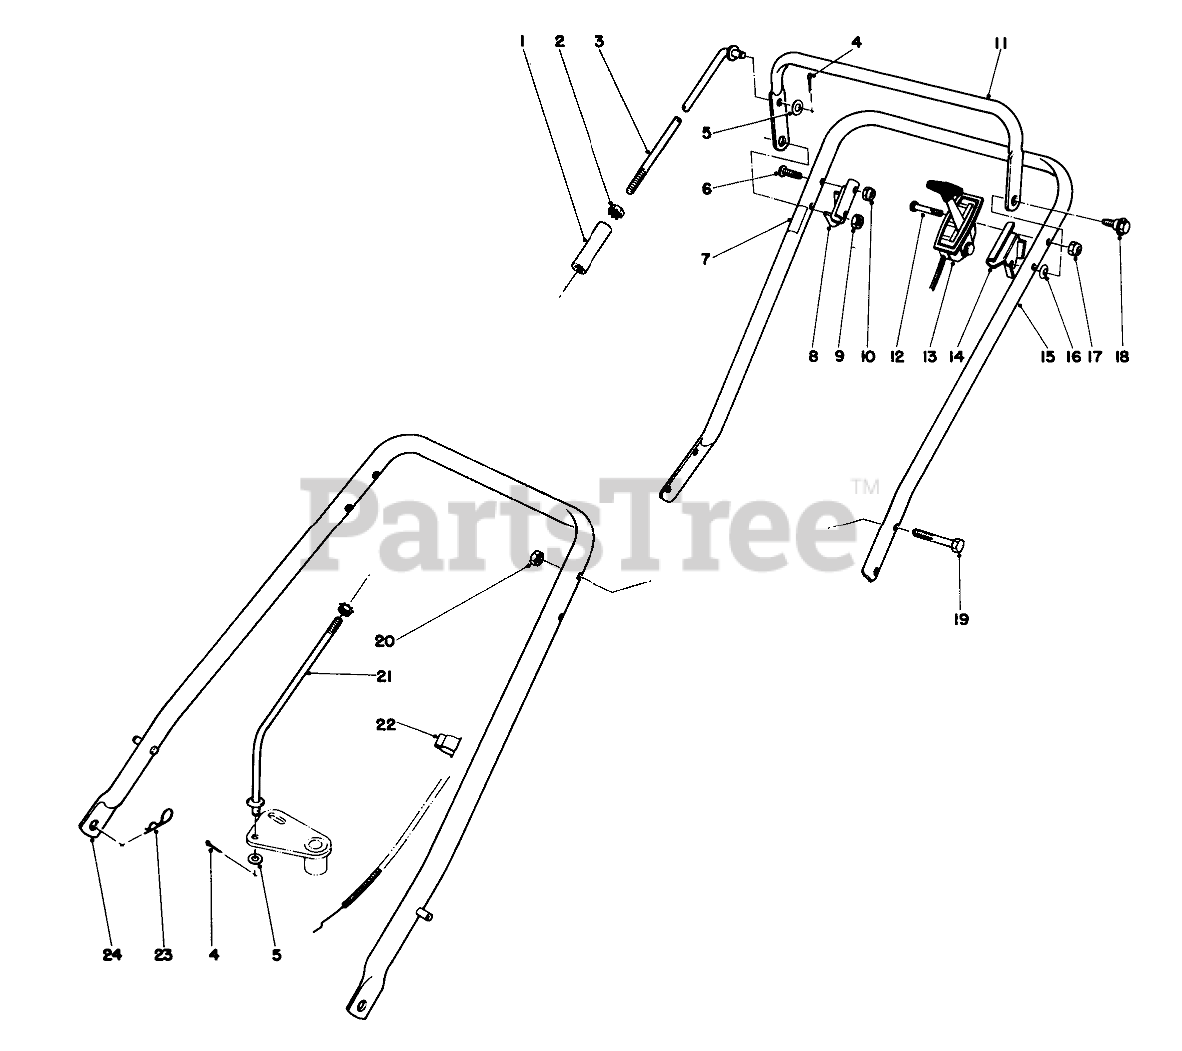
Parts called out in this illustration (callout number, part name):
1	CONTROL ROD SLEEVE
2	NUT-KEPS
3	Control Rod
4	PIN-COTTER
5	WASHER-PLAIN
6	10-24X1-1/4 PAN HD MS
7	Decal
8	CONTROL BAIL BRACKET
9	Nut
10	NUT-LOCK, NI
11	Control Bail
12	10-24X1-1/4 PAN HD MS
13	Throttle Control
14	Bracket-Control Bail
15	UPPER HANDLE
16	WASHER-SPRING
17	NUT-LOCK, NI
18	SCREW-SHOULDER
19	SCREW-HH
20	NUT-LOCK
21	CONTROL ROD
22	Clamp
23	PIN-COTTER, HAIR
24	LOWER HANDLE WA
